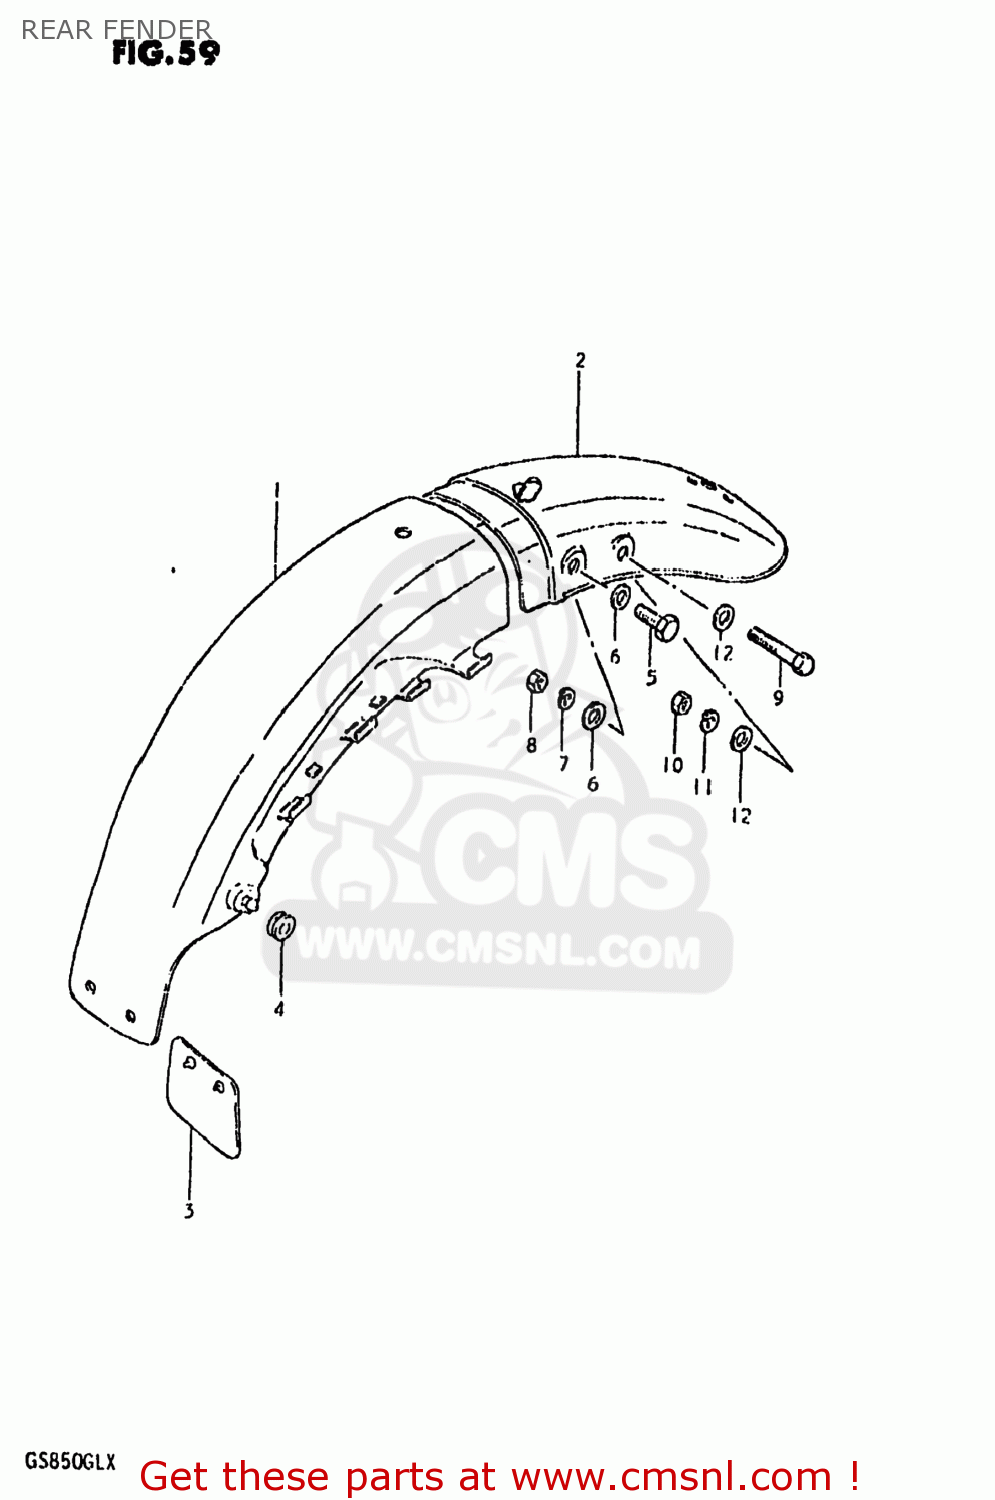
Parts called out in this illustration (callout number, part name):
1	FENDER,REAR
2	FENDER,REAR
3	GUIDE,RR FENDER MUD
4	CUSHION
5	BOLT
6	WASHER
7	LOCK WASHER
8	NUT
9	BOLT
10	NUT 8MM
11	LOCK WASHER
12	WASHER
